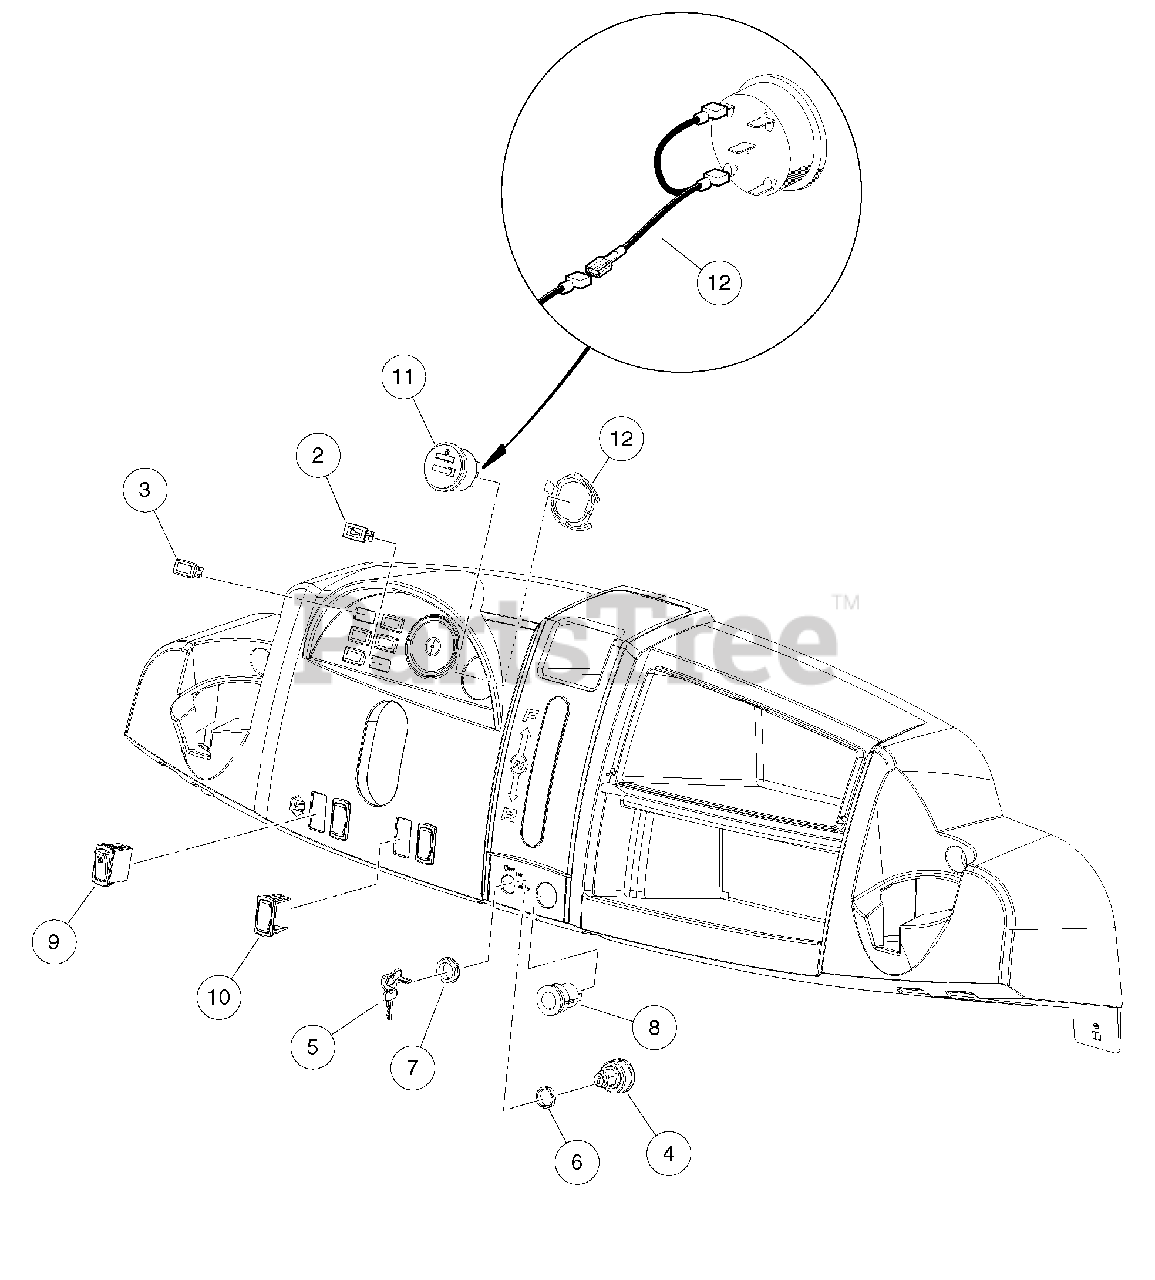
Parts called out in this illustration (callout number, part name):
1	Instl, Elec Sys Awd Gas Fh680d
2	Light, Oil
3	Plug, Hole
4	Key Switch 12v Key Start
6	Spacer, Keyswitch
7	Nut, Key Switch
8	Receptacle, Accessory
9	Switch, Rocker, Light
10	Cover, Hole, Switch, Rocker
11	Gauge Fuel-hour Sep Gnd
12	Clip, Meter, Round
13	Asm Wire Meter F-h Jumper
